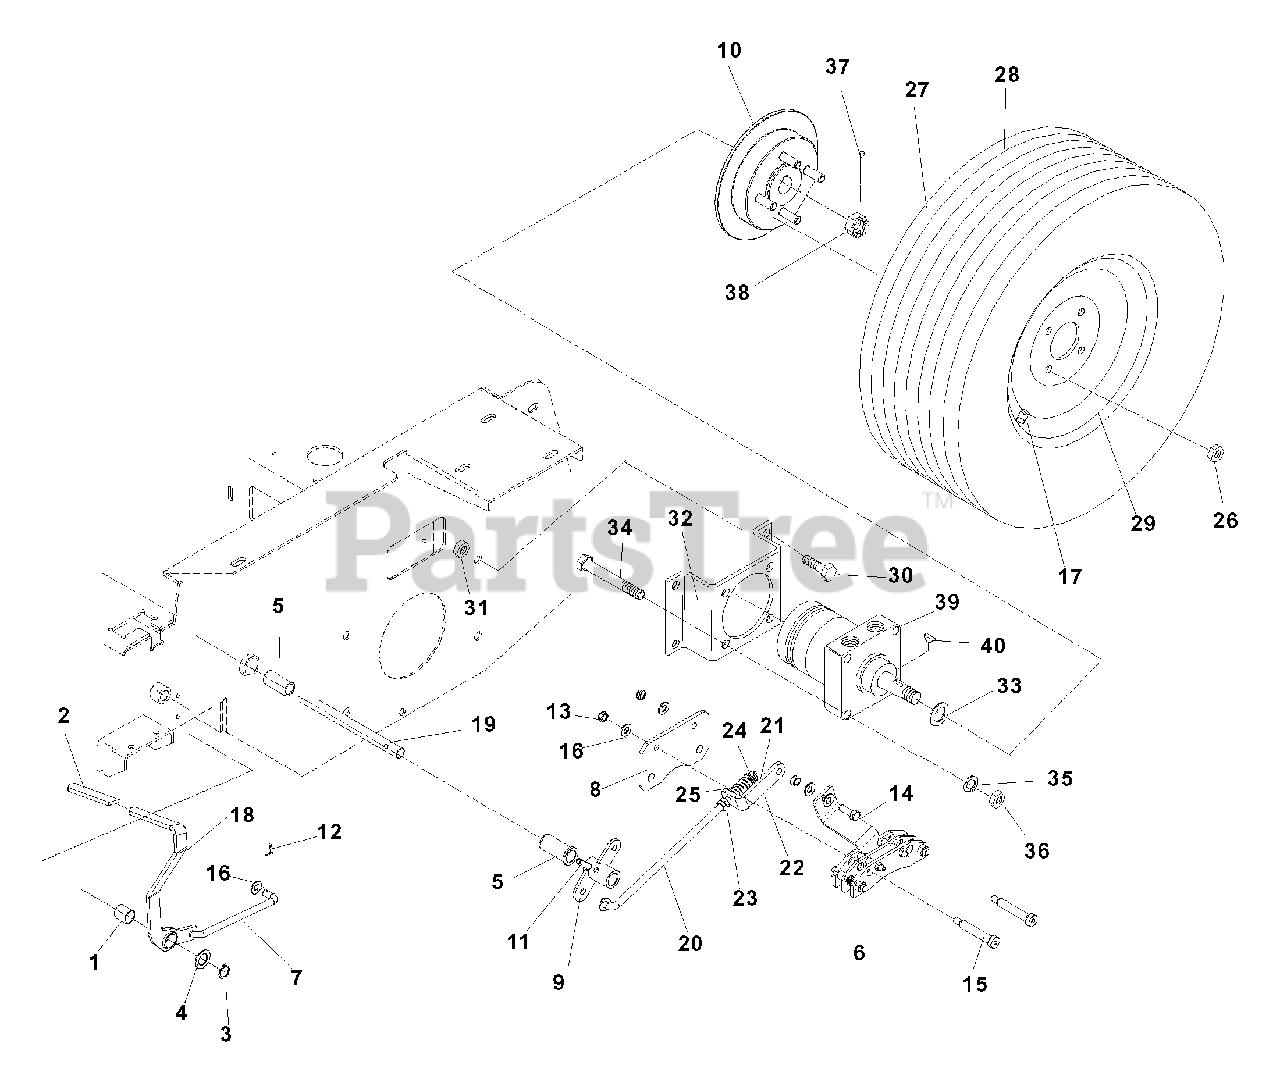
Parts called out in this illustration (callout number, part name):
3	RING, RETAINING, 7/8
4	BUSHING, MACHINE
5	BUSHING, POLYMER, 3/4 x 2
6	CALIPER
7	LINKAGE, BRAKE
8	PLATE, BRAKE
9	BELLCRANK, BRAKE
11	PIN, ROLL, 5/16" DIA.
12	PIN, COTTER, 3/32 x 3/4
13	NUT, 3/8 -16, JAM, NYLOC
14	HCS, 3/8 -16 x 1, GR5
15	SB, 3/8 -16 x 2 1/2 , SKT HD
16	WASHER, 3/8, SAE
17	VALVE STEM
18	BRAKE LEVER
19	SHAFT, CROSS
20	LINKAGE, REAR BRAKE
21	NUT, 3/8 -24, CTR LK, GR5
22	BRACKET, L
23	NUT, 3/8 -24, JAM
24	WASHER, 3/8 , SAE
26	NUT, LUG, 1/2F
27	TIRE, COMPLETE, 61" & 72"
27	TIRE, COMPLETE, 52"
28	TIRE, 24 x 12.0-12
28	TIRE, 23 x 9.5-12
29	RIM, 2 1/2"
29	RIM, OFFSET 1"
30	HFCS, 1/2C x 1 1/4
31	NUT, 1/2C, NYLOC
32	STANDOFF, WHEEL MOTOR
33	BUSHING, MACHINE, 1"
34	HCS, 1/2 -13 x 2 3/4, GR5
35	LOCKWASHER, 1/2
36	NUT, 1/2 -13
37	PIN, COTTER
38	CASTLE NUT
39	WHEEL MOTOR, TL15
40	KEY, WOODRUFF
